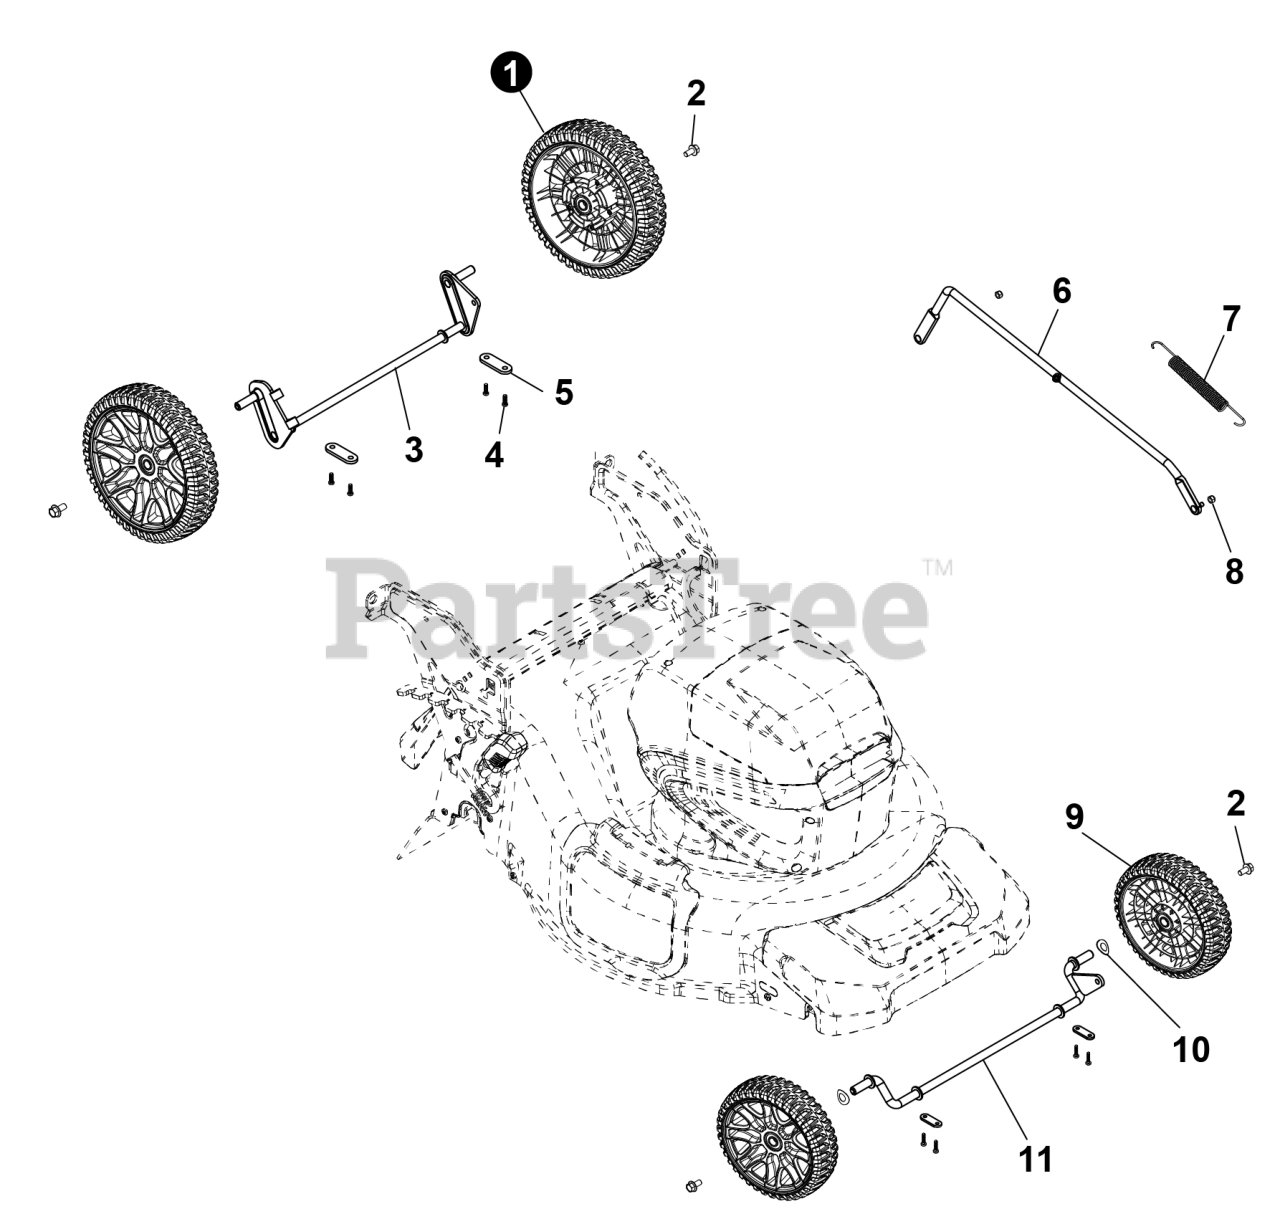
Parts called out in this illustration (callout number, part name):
2	BOLT, WHEEL
3	AXLE,REAR
5	BRACKET, AXLE RETAINER
6	HEIGHT ADJUSTER
11	AXLE, FRONT
